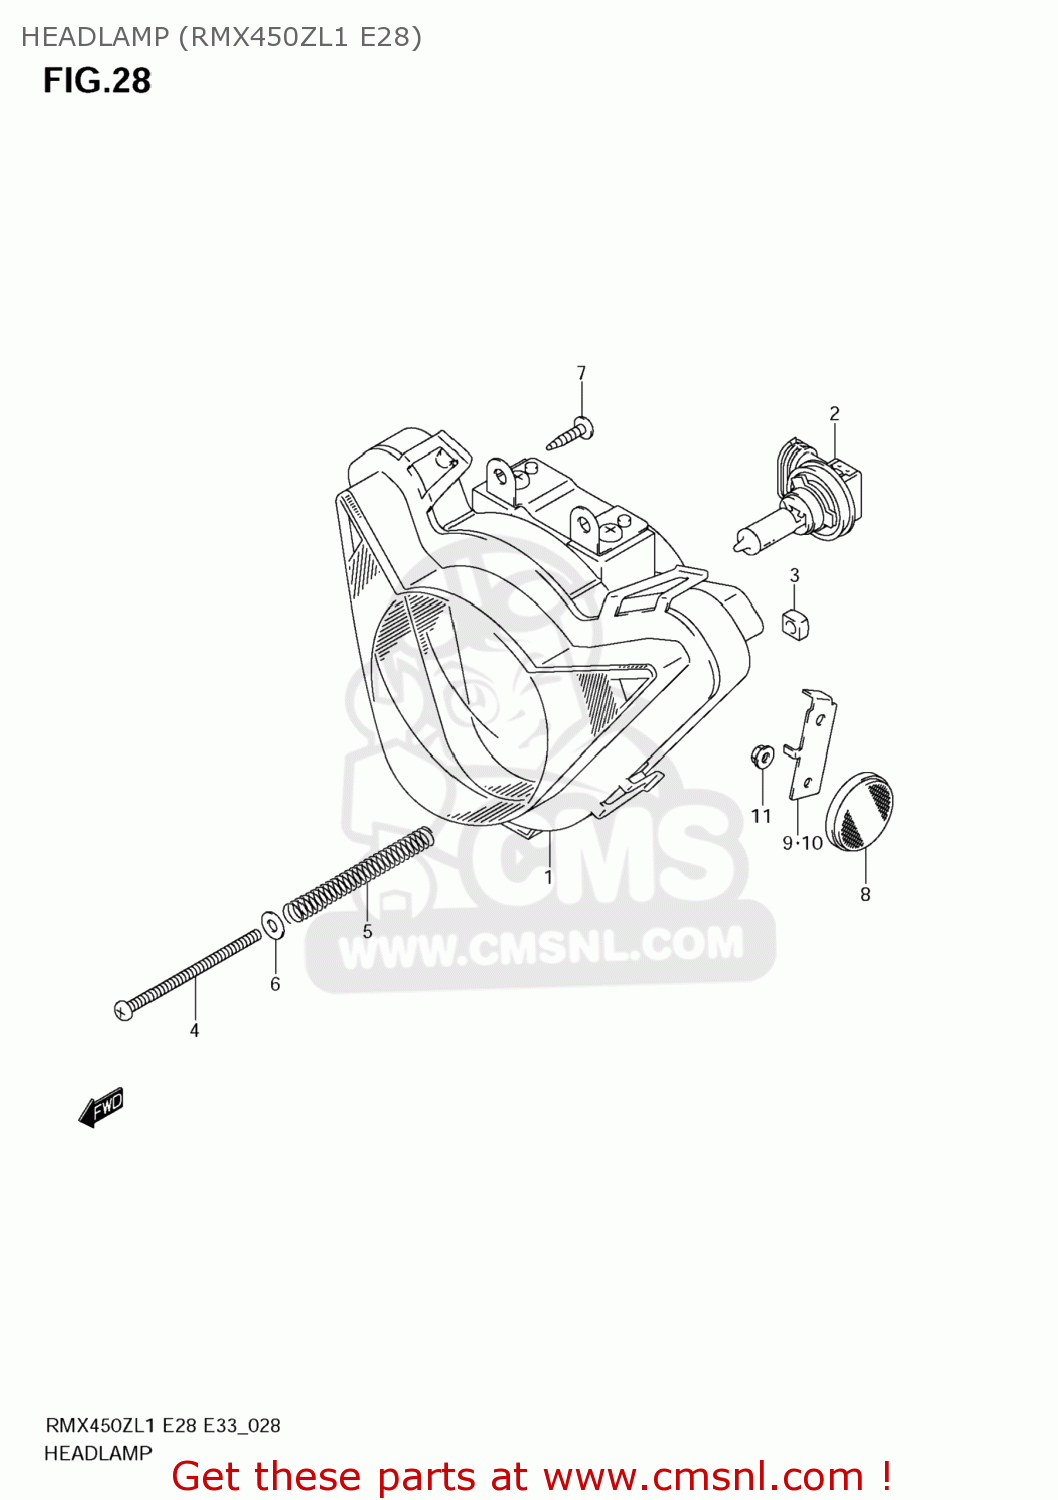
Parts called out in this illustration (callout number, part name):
1	HEADLAMP ASSY
2	BULB(12V35W,H8)
3	NUT,HEADLAMP
4	SCREW,HEADLAMP ADJUSTER
5	SPRING,HEADLAMP ADJUST
6	WASHER
7	SCREW
8	REFLEX REFLECTOR ASSY,FR SIDE
9	BRACKET,FR SIDE RR,R
10	BRACKET,FR SIDE RR,L
11	NUT
